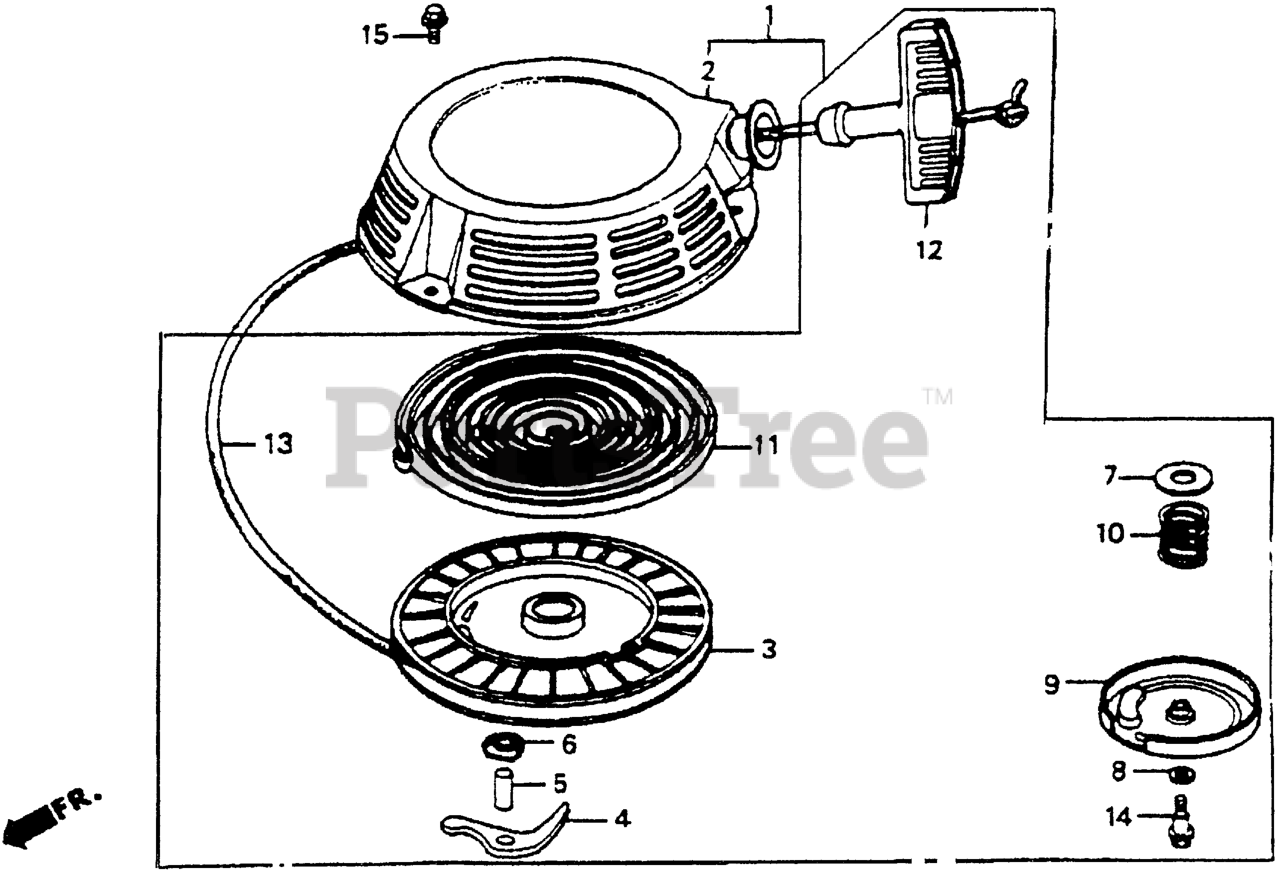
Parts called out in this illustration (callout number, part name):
1	STARTER ASSY., RECOIL *R8* (BRIGHT RED)
2	CASE, RECOIL STARTER *R8* (BRIGHT RED)
3	REEL, STARTER
4	RATCHET, STARTER
5	SHAFT, RATCHET
6	PLATE, GUIDE
7	PLATE A, FRICTION
8	PLATE B, FRICTION
9	COVER, REEL STARTER
10	SPRING, FRICTION
11	SPRING, RETURN
12	GRIP, STARTER
13	ROPE, STARTER (#6X64") (Honda Code 2106433). (N/A: USE ALT P/N 08560-ZG921-11)
14	BOLT, REEL COVER
15	BOLT, FLANGE (6X10)
